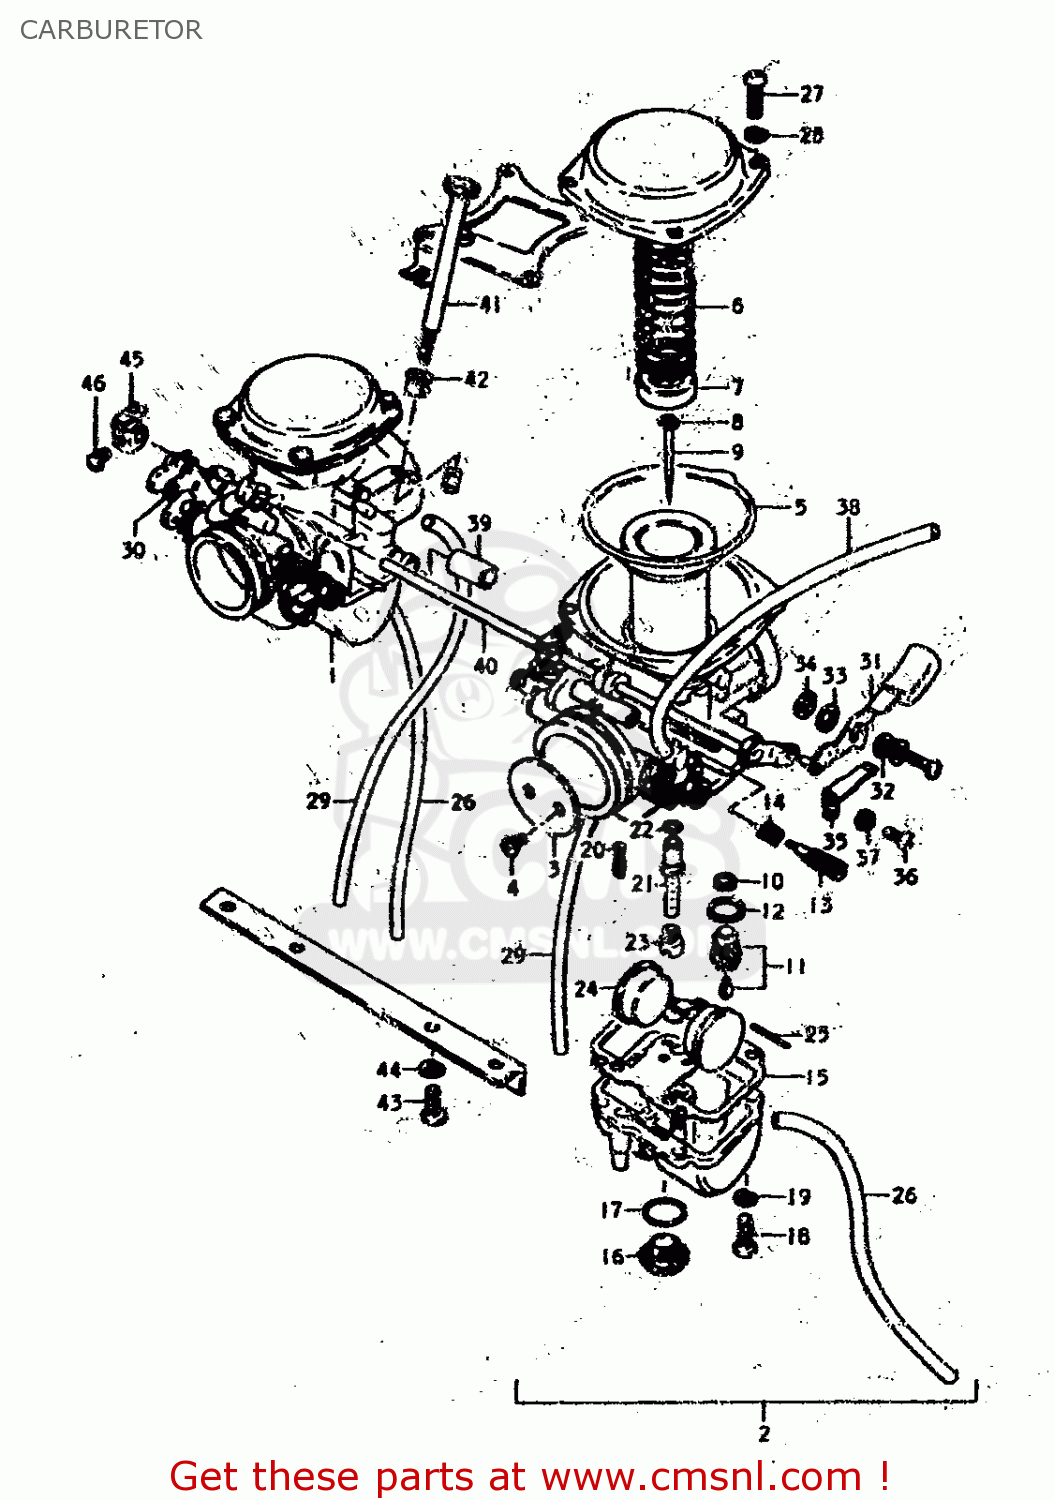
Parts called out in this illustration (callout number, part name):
1	CARBURETOR ASSEMBLY
2	CARBURETOR ASSEMBLY
3	VALVE,THROTTLE
4	SCREW
5	DIAPHRAGM ASSY
6	SPRING,DIAPHRAGM
7	CONNECTOR
8	CLIP
9	NEEDLE,JET
10	FILTER
11	VALVE ASSY,NEEDLE
12	GASKET,MAIN JET HOLDER (NAS)
13	SCREW,PILOT AIR
14	SPRING,THROTTLE SCREW
15	GASKET,FLOAT CHAMBER (NAS)
16	SCREW,GUIDE
17	O-RING
18	SCREW
19	LOCK WASHER
20	JET,PILOT
21	JET,NEEDLE
22	O-RING
23	SET, MAIN
24	FLOAT
25	PIN,FLOAT
26	HOSE
27	SCREW
28	LOCK WASHER
29	HOSE
30	GASKET
31	LEVER
32	WASHER,STARTER LEVER
33	WASHER,STARTER LEVER
34	RING,STARTER LEVER
35	SPRING
36	SCREW
37	LOCK WASHER
38	HOSE
39	HOSE
40	SHAFT,STARTER
41	ADJUSTER
42	BUSH
43	SCREW 6X12
44	LOCK WASHER
45	LEVER, STARTER
46	SCREW
